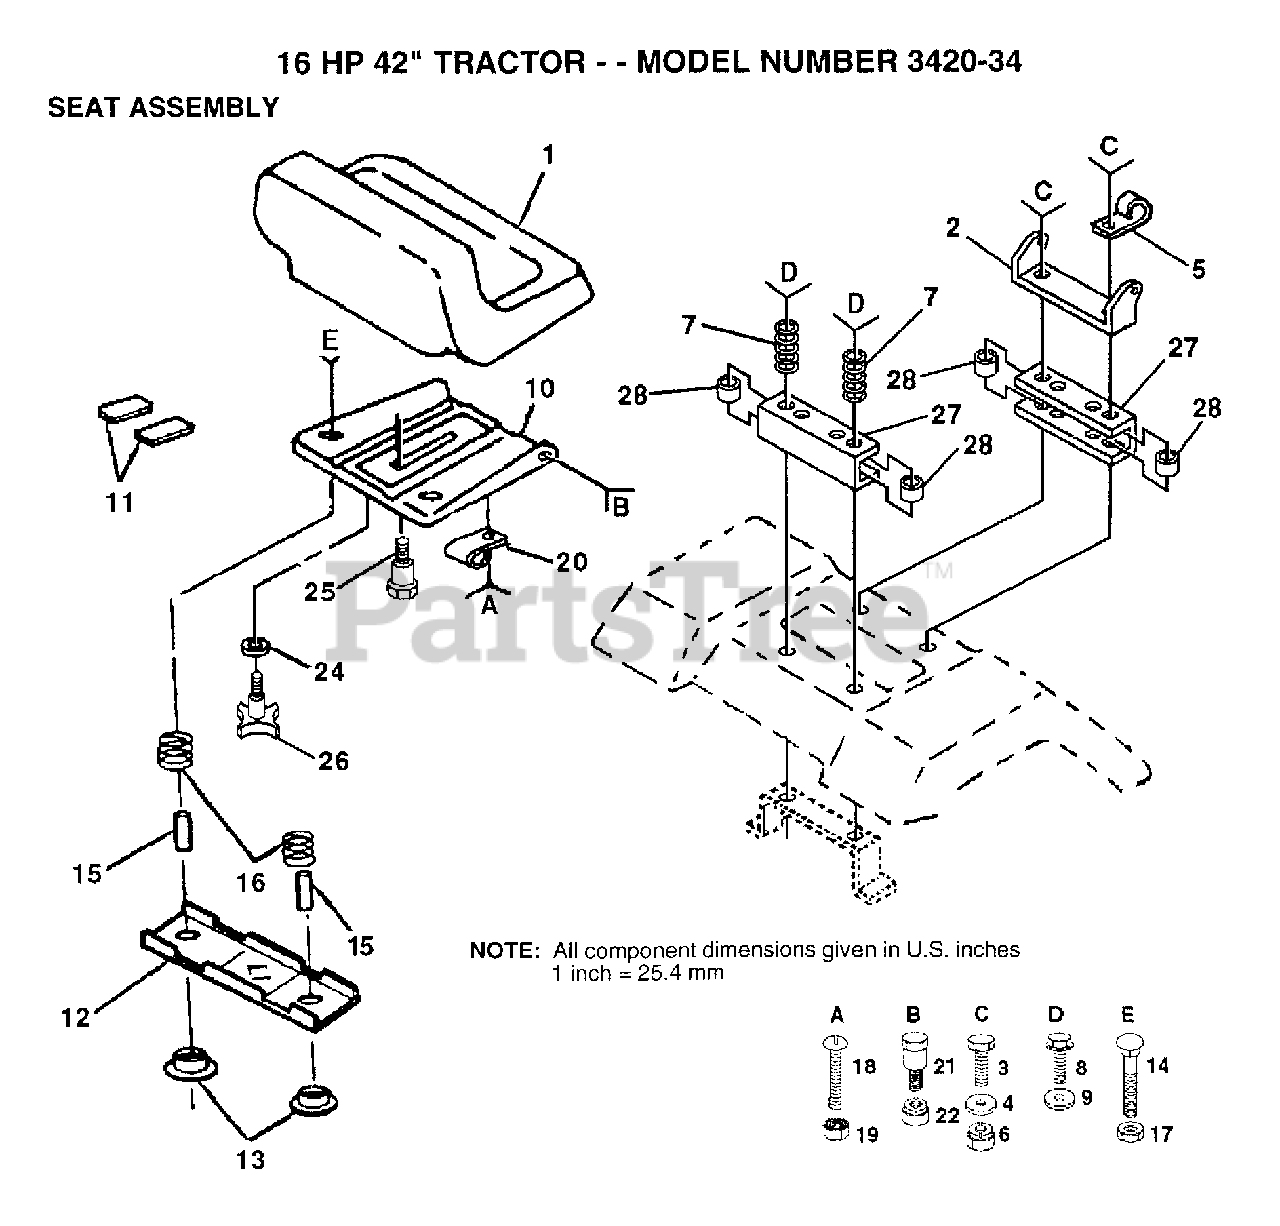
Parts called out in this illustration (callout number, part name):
3	BOLT
4	WASHER PM
5	CLIP T
7	SPRING COMPRESSIO
8	SCREW
9	WASHER
11	STRIP FORM
12	BRKT SWITCH
13	BUSHING
15	SPACER SPLIT
16	SPRING COMPRESSED
19	"NUT,KEPS"
24	WASHER
25	"BOLT,SHOULDER"
26	"KNOB 1/2"" YT"
27	SEAT SPACER
28	SPLIT SPACER
